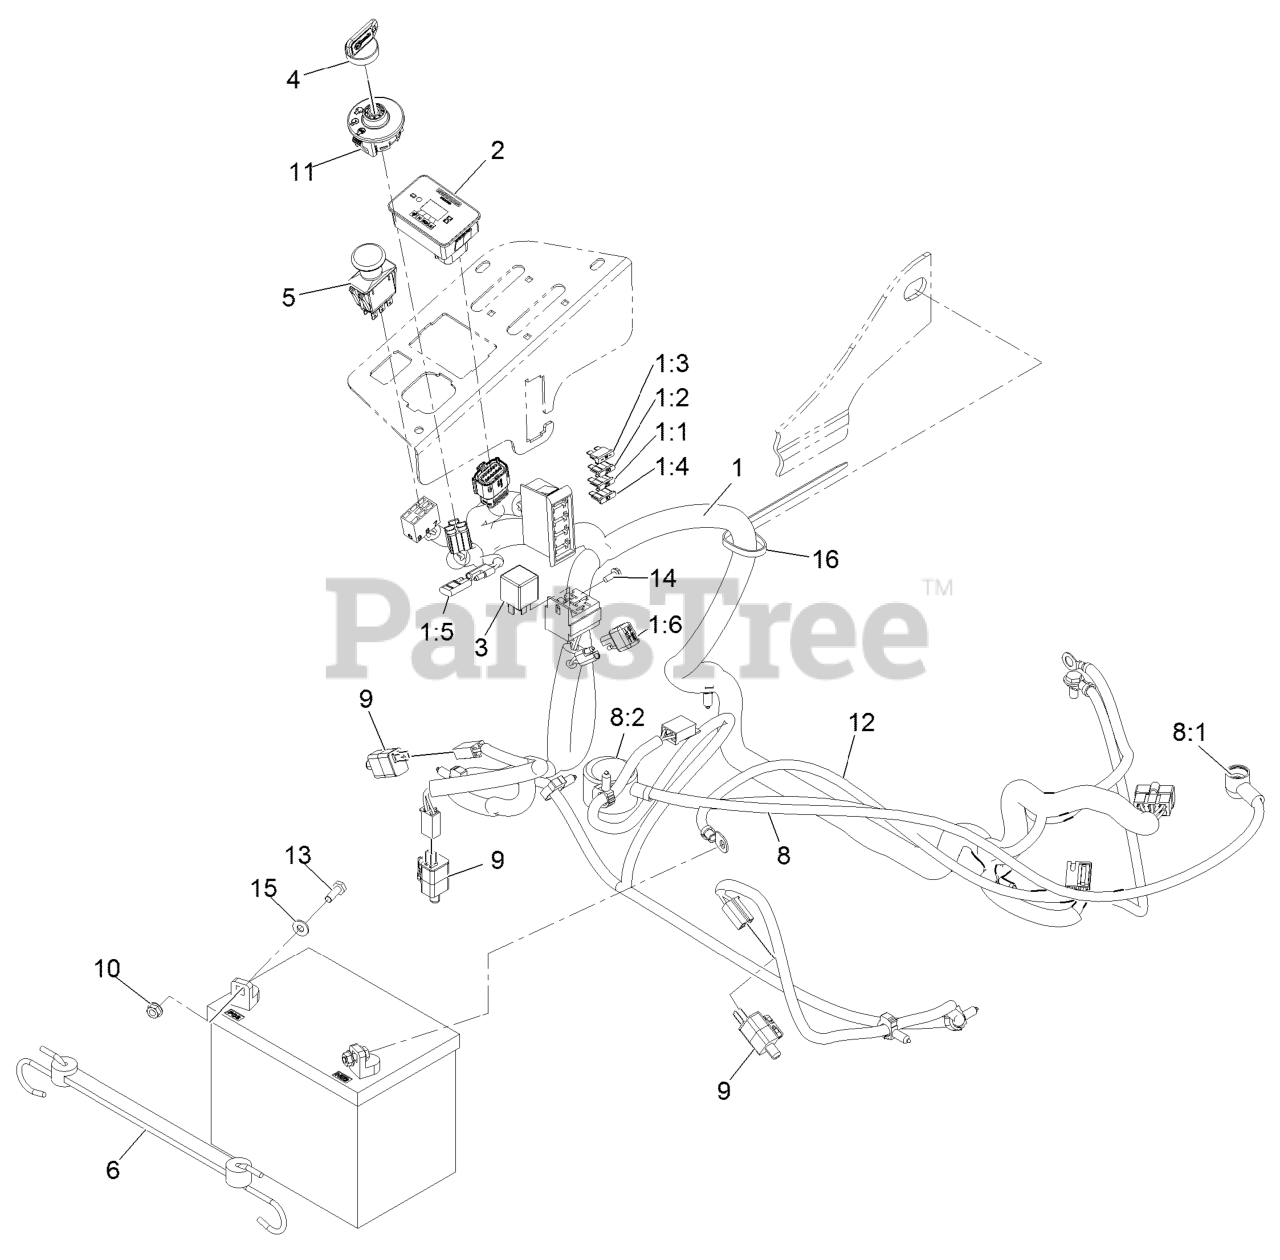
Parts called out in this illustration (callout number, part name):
1	HARNESS, WIRE
1:1	FUSE-BLADE, 25 AMP
1:2	FUSE-BLADE TYPE, 20 AMP
1:3	FUSE-BLADE, 15 AMP
1:4	FUSE-BLADE, 10 AMP
1:5	CAP-PLUG
2	MODULE ASM
4	KEYS-IGNITION (SPARE PAIR
4	KEY-IGNITION
5	SWITCH-PTO
6	HOLDDOWN-BATTERY
8	POSITIVE BATTERY CABLE AS
8:1	INSULATOR-BATTERY
8:2	INSULATOR-SOLENOID
12	CABLE-BATTERY, NEGATIVE
13	SCREW-HH
14	SCREW-TAPTITE
15	WASHER-FLAT
16	TIE-PLASTIC
